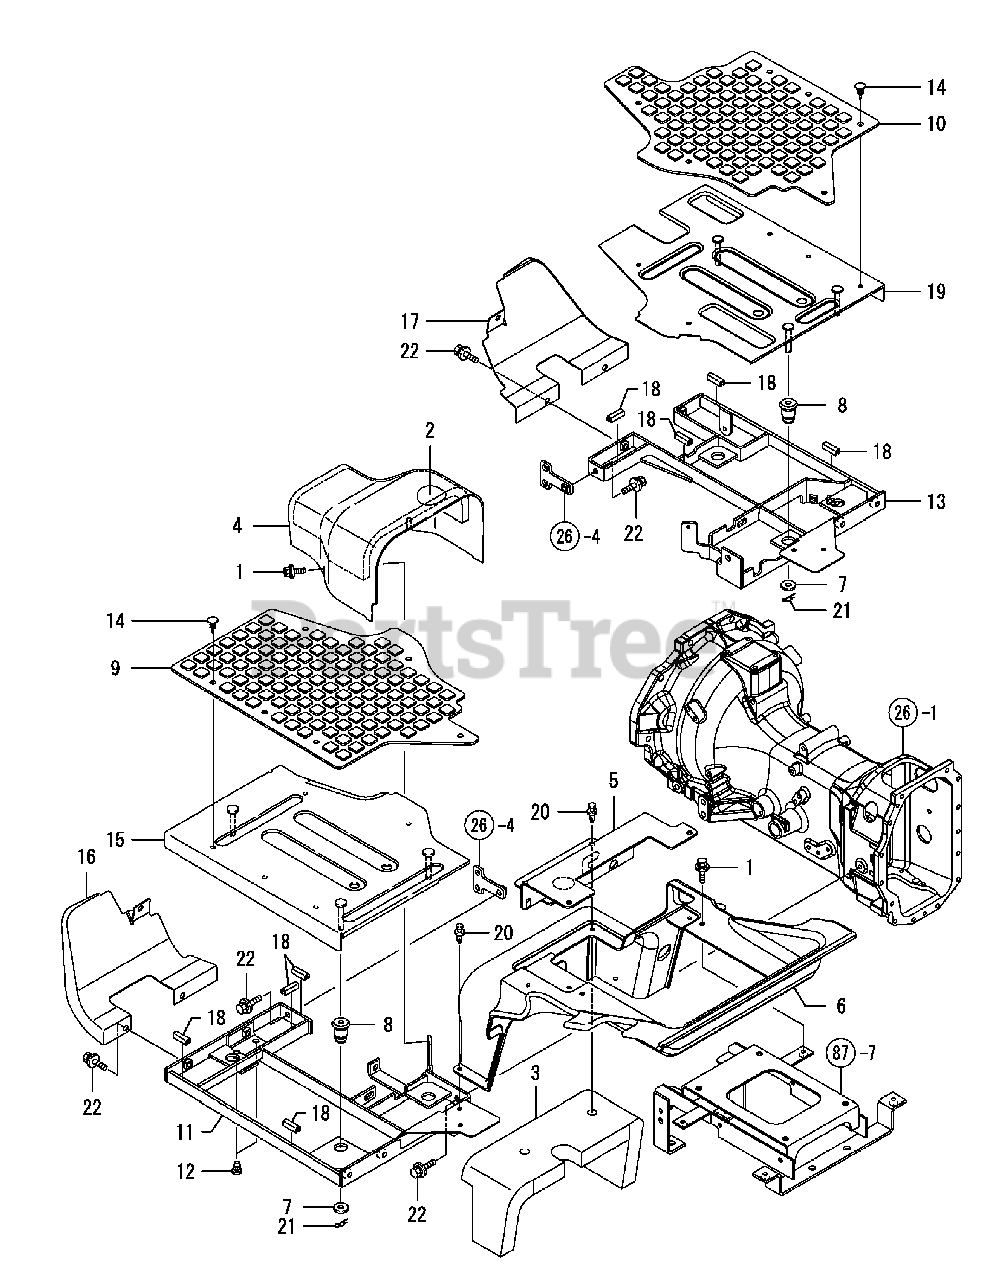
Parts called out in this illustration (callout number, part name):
4	Cover Assy-H, Front
5	Seat Close Out Cover
6	Seat Close Out
8	Rubber,Step Vibprf.
9	Rubber, Step L
10	Rubber, Step R-H
11	Frame Assy, Step L
12	Stopper, Pedal
13	Frame Assy, Step R
16	Foot Cover L Cmp
17	Foot Cover R Cmp
21	Snap Pin (Jaso 8)
